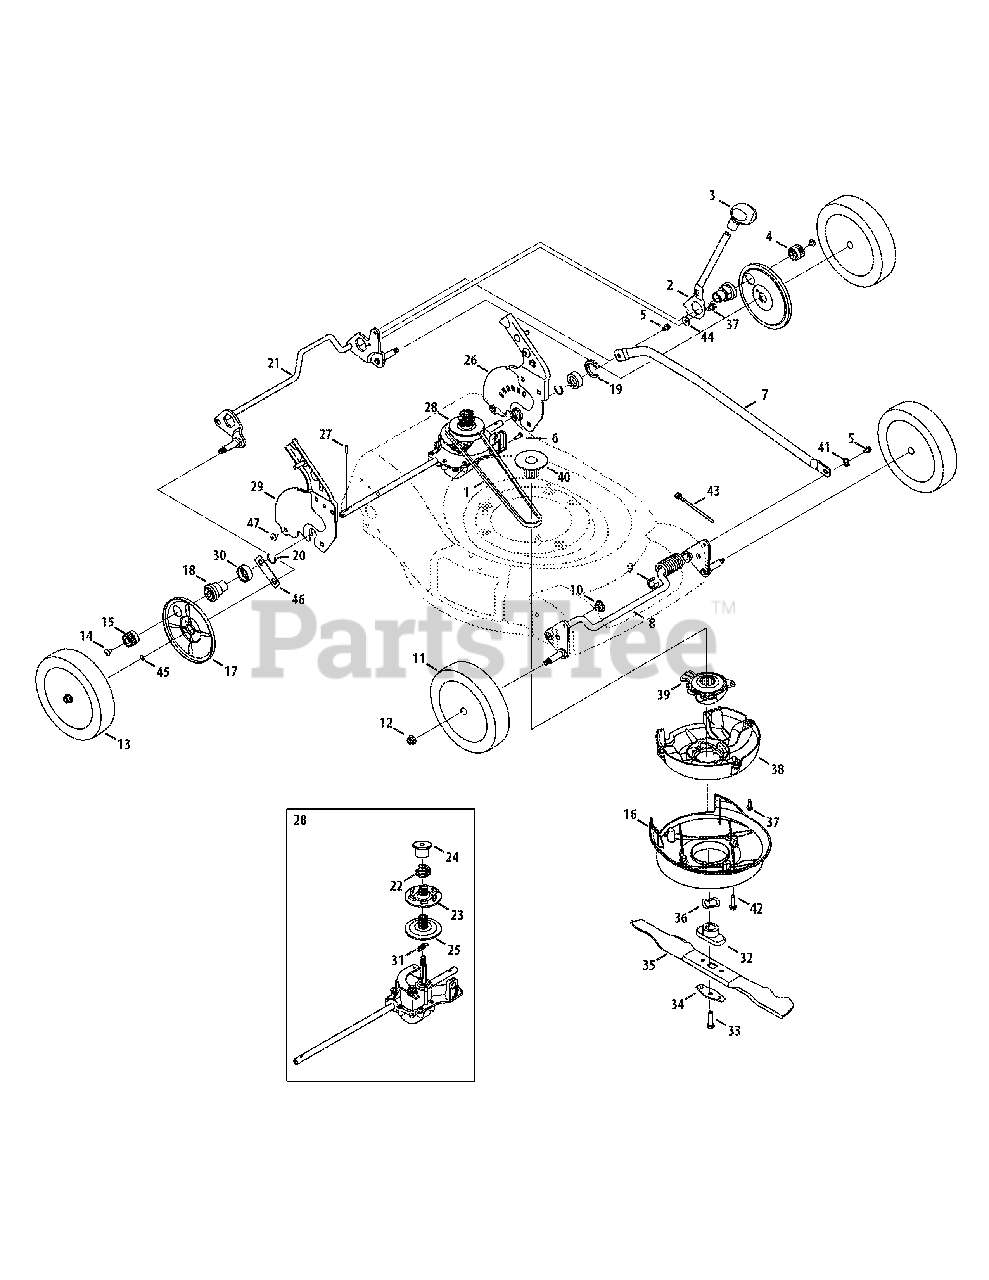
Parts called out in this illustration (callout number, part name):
1	V-Belt
4	Spur Gear 14T LH
5	Shoulder Screw 1/4-20 x .50
6	Screw, #12-16
8	Front Bracket Assembly
10	Split Hex Flange Bearing
11	Fr. Wheel 8 x 2.125 Grey Idle S-Wave
12	Hex L-FlangeNut 3/8-16 Gr. F, Nylon
13	Rear Wheel Ass'y 8" TVS S-Wave Grey
14	Pan Scr. 1/4-20 x .390
15	Spur Gear 14T RH
17	Wheel Dust Cover
18	Transmission Bearing Support
20	Retaining Ring .875
21	Rear Bracket Assembly
22	Compression Spring
23	Upper Pulley
26	Handle Bracket Ass'y LH
28	Transmission Assembly
29	Handle Bracket Ass'y LH
30	Bearing Support Spacer
31	Extension spring
32	Blade Adapter
33	Screw, 3/8-24 x 1.50
34	Blade Bell Support
35	21" Mulching Blade
36	Space Washer
37	Hex Wash S-Tapp Scr 1/4-20 x .50
38	Engine Baffle
39	Lower Pulley Assembly
42	Screw 1/4-15 x 1.250
44	Cupped Washer .340 x .872 x .080
45	Ring, .375 ID x .054
